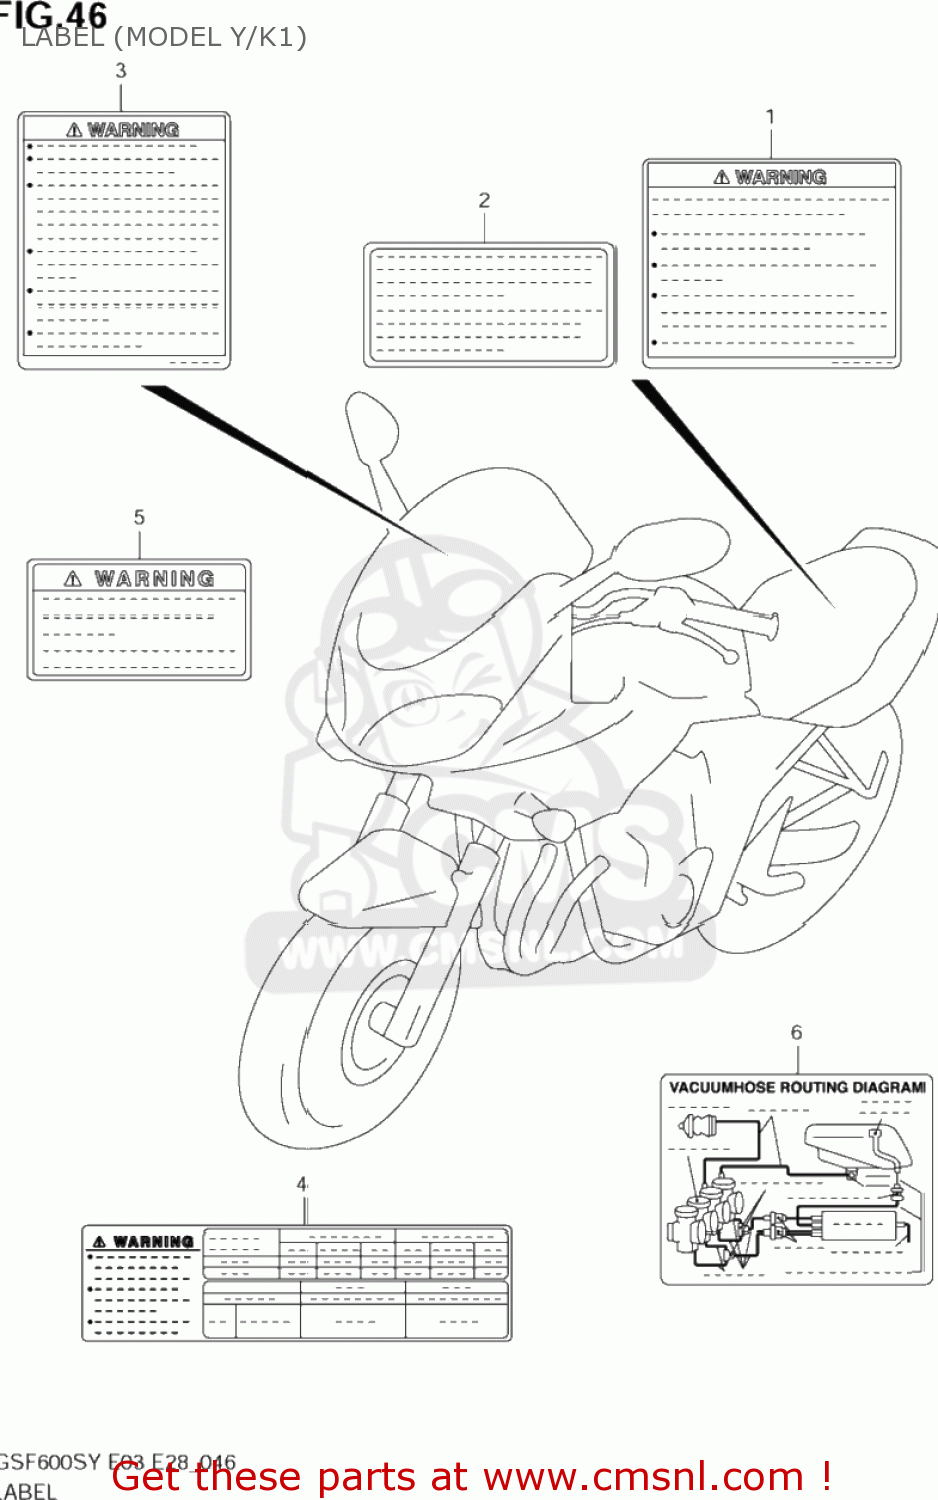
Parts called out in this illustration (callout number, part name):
1	LABEL,GENERAL WARNING
2	LABEL (MANUAL NOTICE)
3	LABEL,WARNING SCREEN
4	LABEL,TIRE INF
5	LABEL,WARNING STEERING
6	LABEL,VACUUM HOSE ROUTING
7	MANUAL,OWNER'S GSF600/S
